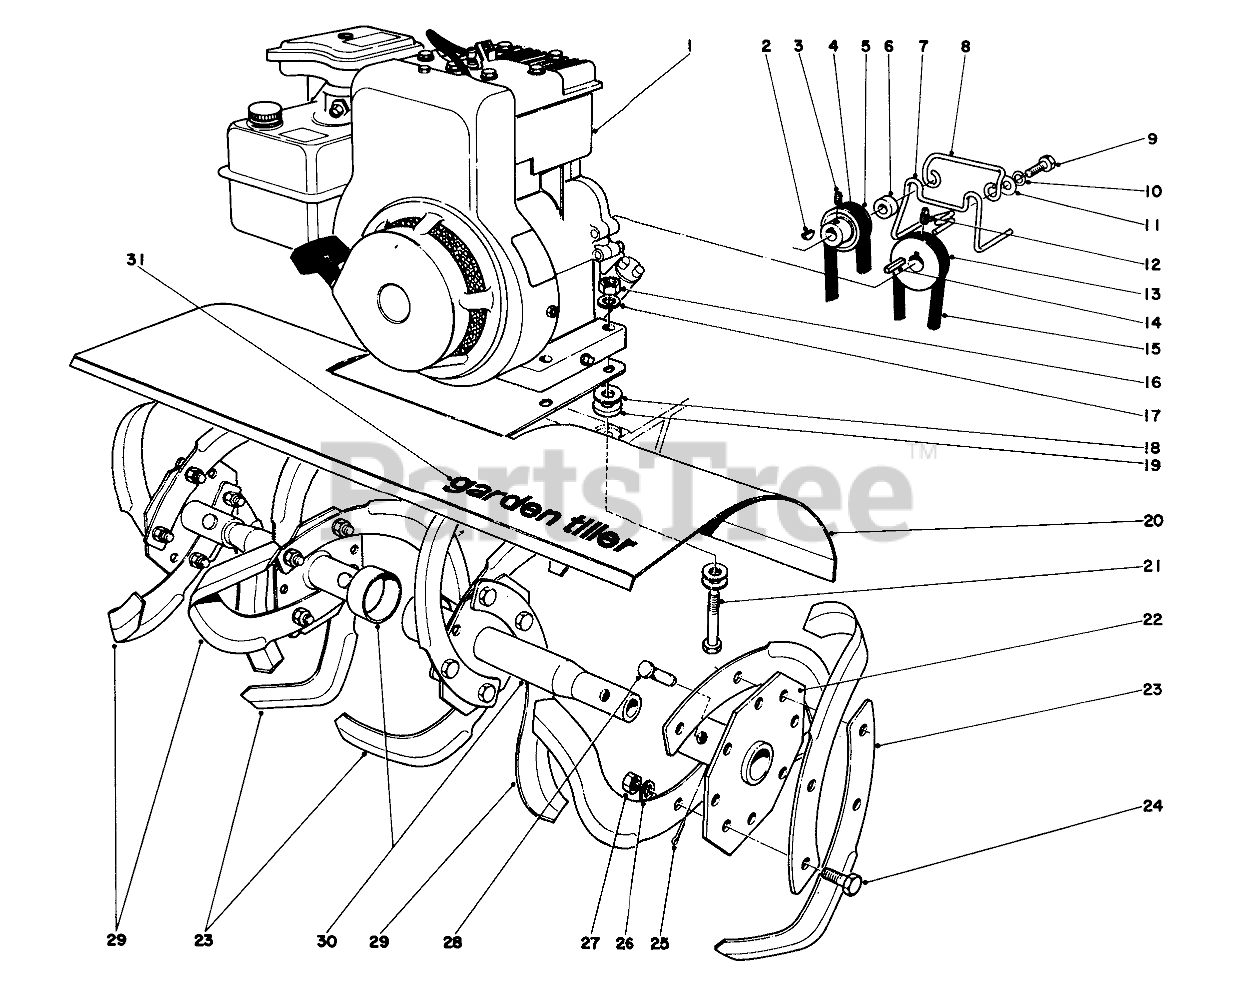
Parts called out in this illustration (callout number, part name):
1	Engine
2	KEY-WOODRUFF
3	SCREW-SET
5	Pulley
6	SPACER
7	Upper Belt Guide
8	Cover Latch
9	SCREW-HH
10	WASHER-LOCK
11	WASHER-FLAT
12	SCREW-SET, HSH
13	Engine Pulley
14	KEY-SQUARE
16	NUT-HEX
17	WASHER-LOCK
18	WASHER-FLAT
19	WASHER-FLAT
20	Shield
21	SCREW-HH
22	Axle Hub
23	RH TINE
24	SCREW-HH
25	PIN-COTTER
26	WASHER-LOCK
27	NUT-HEX
28	TINE PIN
29	LH TINE
30	Axle Hub
31	Decal
